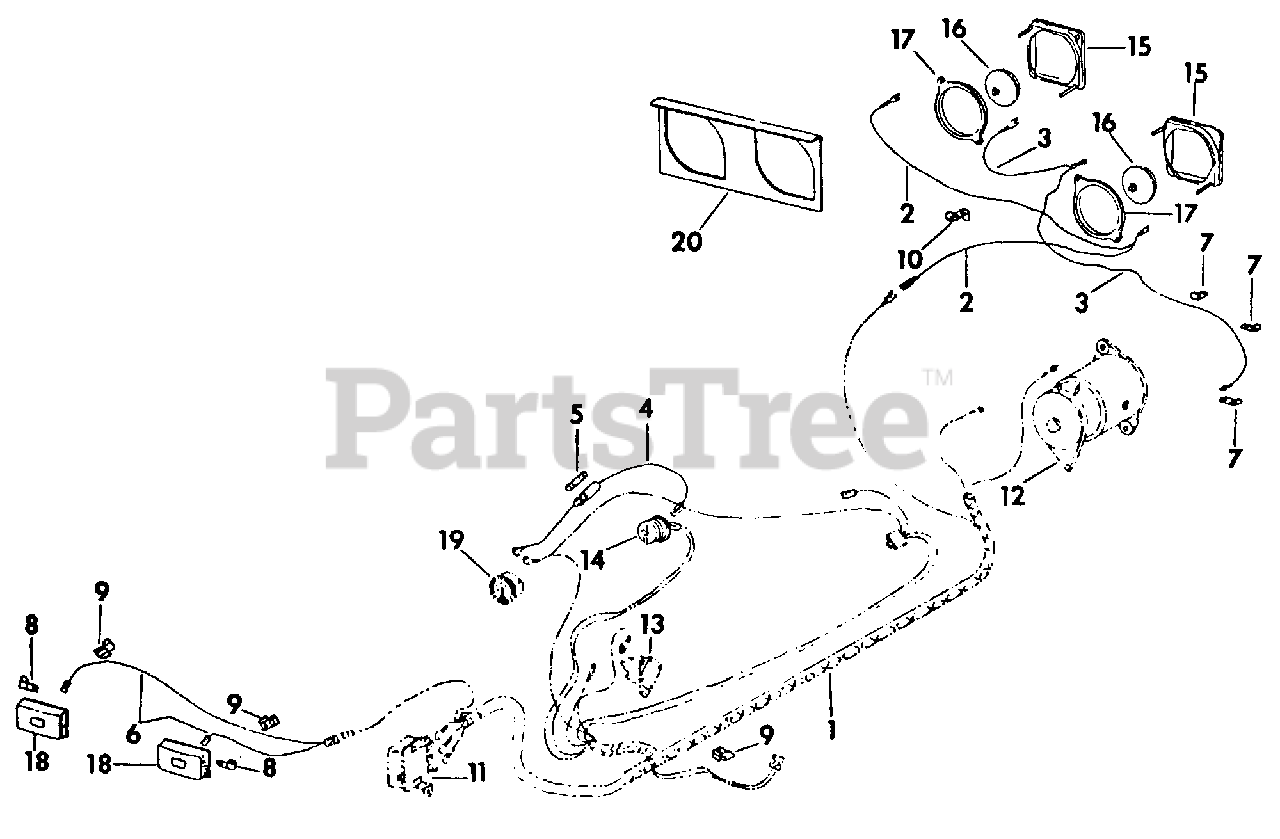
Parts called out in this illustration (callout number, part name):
1	Harness, Cable
2	Cable, Headlight
3	Cable, Headlight to Ground
4	Cable, Switch to Charge Indicator
5	Fuse, 10 Amp Slo-Blo
6	Cable, Taillight
7	Clip, Cable
8	Clip, Taillight
9	Clip, Safety Starting Switch Cable
11	Regulator, Voltage
12	Starter-Generator Assy
13	Switch, Magnetic
14	Switch, Lighting
15	Rim, Headlight
16	Unit, Sealed Beam
17	Ring, Headlight Clamp
18	Taillight Assy
19	Indicator, Charge
20	Panel, Headlight Mounting
